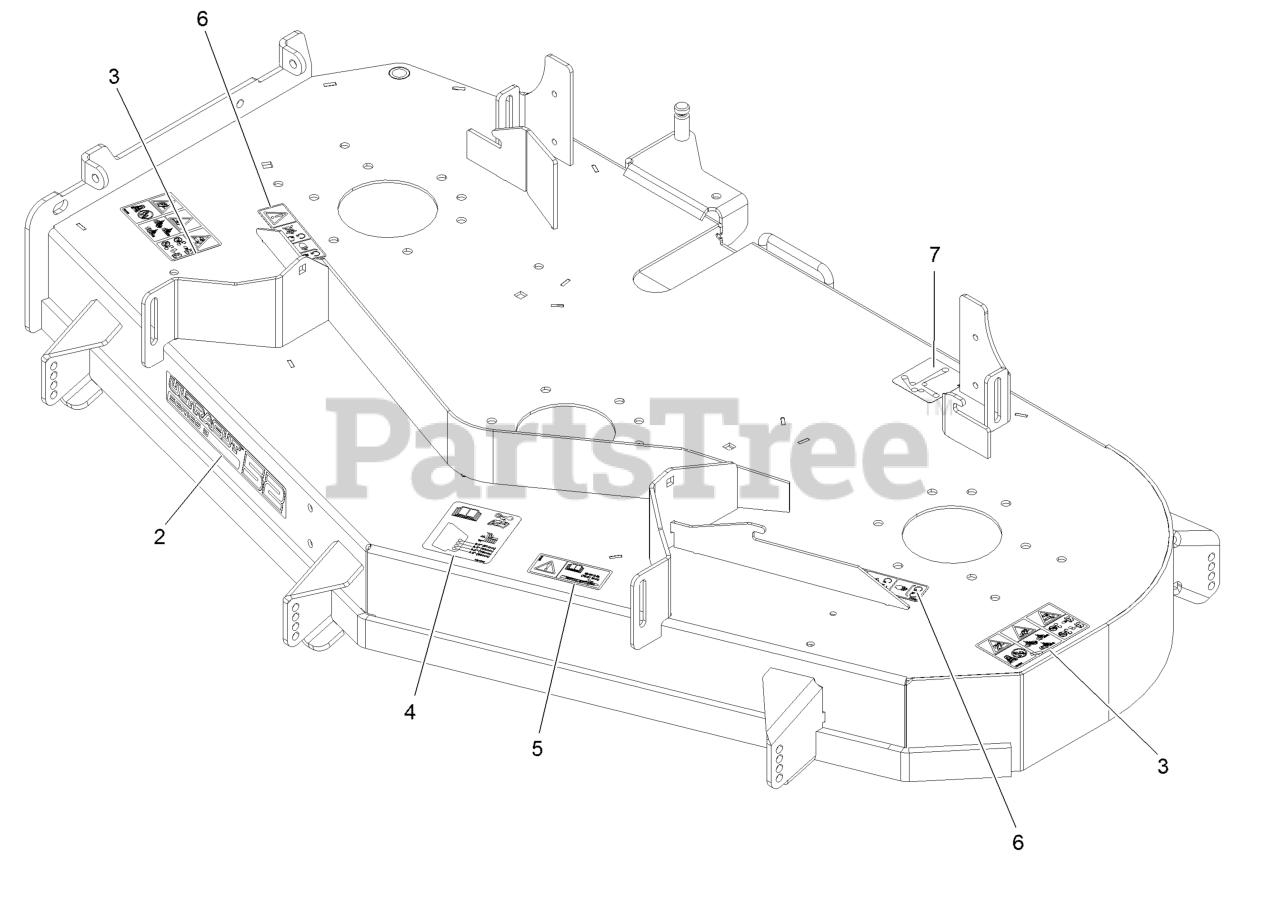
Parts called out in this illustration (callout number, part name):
2	Decal-Ultracut 52 Series
3	Decal-Danger Thrown Objects
4	Decal-Roller, Anti-Scalp
5	Decal-Bolt Torque
6	Decal-Cover, Missing
7	Decal-Routing, Belt
